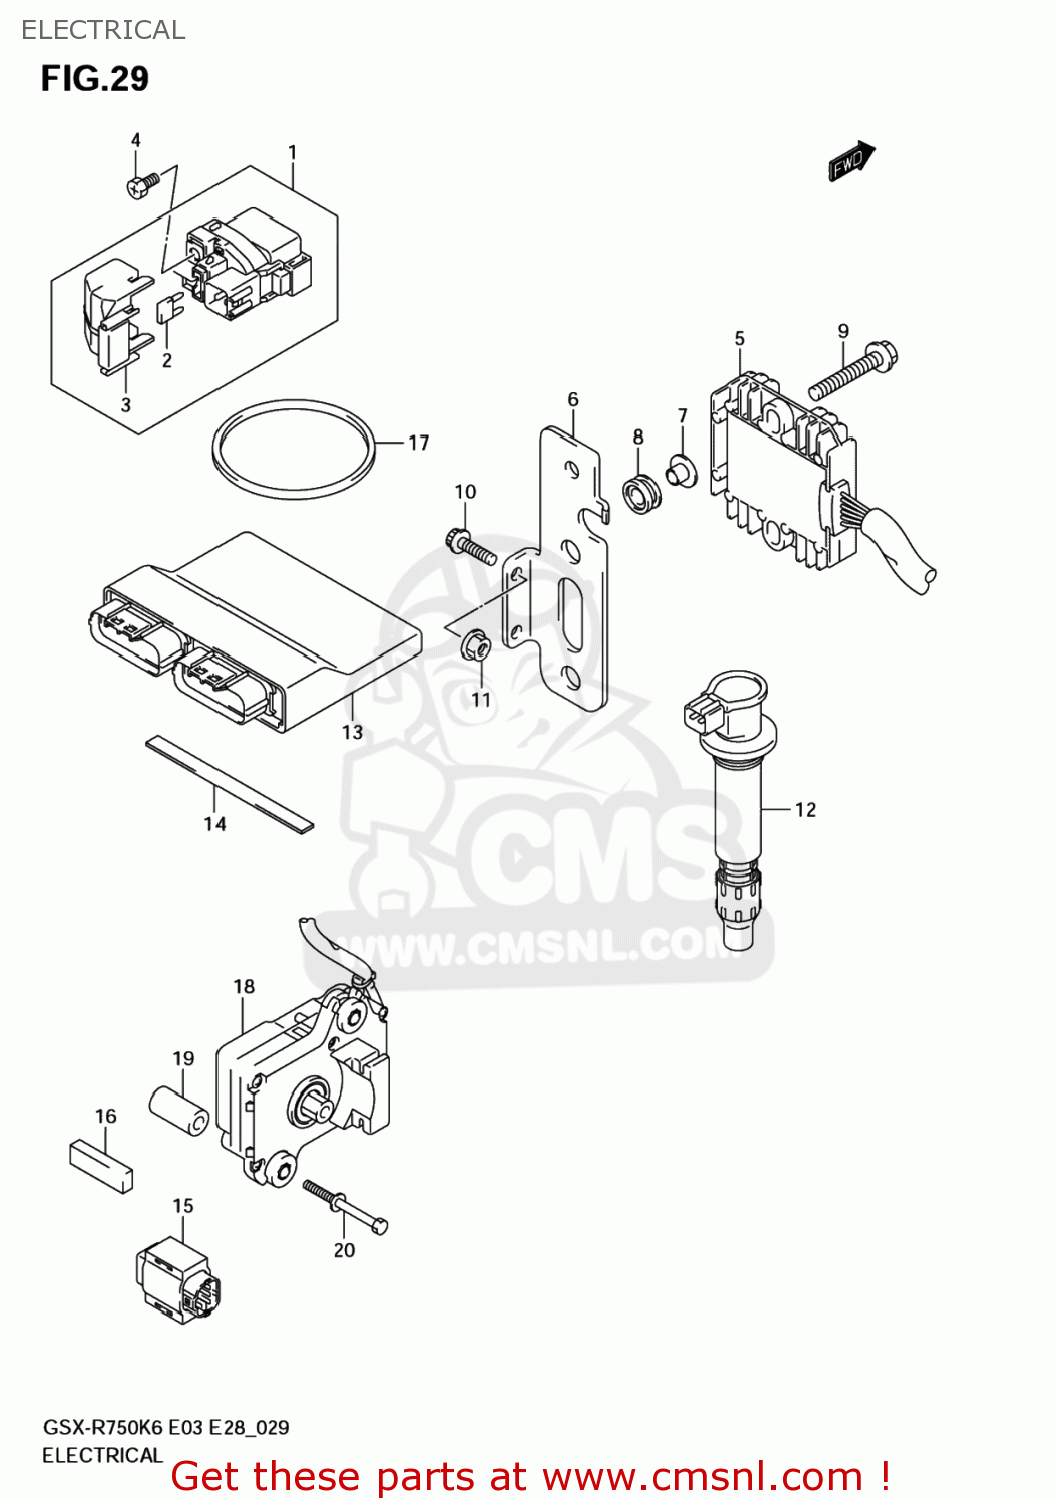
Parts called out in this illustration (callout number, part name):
1	RELAY ASSY,STARTING MOTOR
2	FUSE(30A)
3	COVER
4	SCREW(6X8)
5	RECTIFIER ASSY
6	BRACKET,RECT FIG
7	SPACER(6.2X8.4X6.9)
8	CUSHION
9	SCREW
10	BOLT
11	NUT
12	COIL ASSY,IGNITION
13	CONTROL UNIT,FI
14	CUSHION(130X10X2)
15	SENSOR ASSY,FUEL CUT
16	CUSHION
17	O RING(D:3.5,ID:76)
18	ACTUATOR ASSY,EXHAUST CONTROL
19	SPACER(6.2X14.5X26)
20	BOLT
